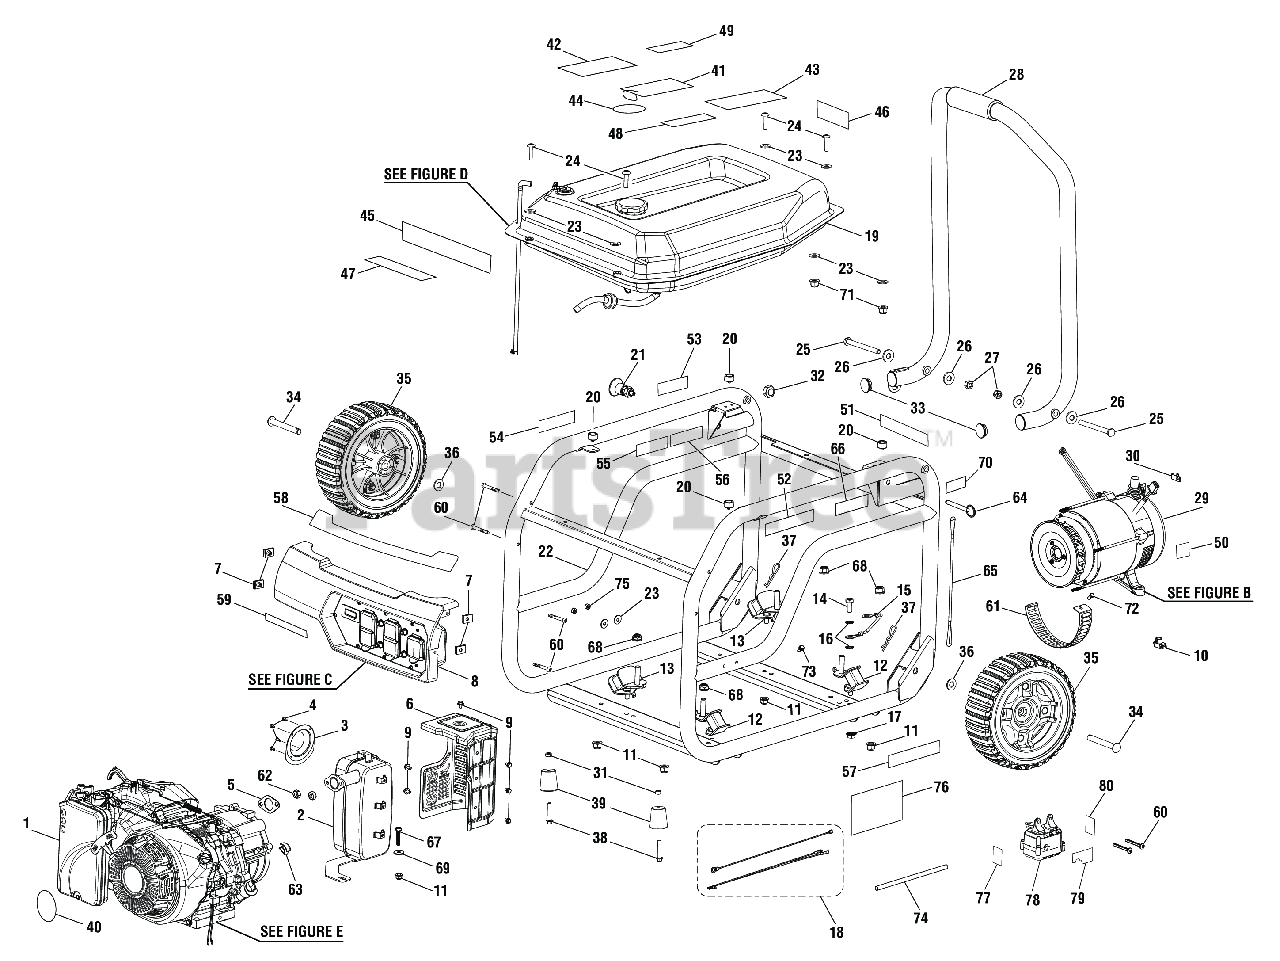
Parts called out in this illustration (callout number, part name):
3	Spark Arrester Screen
4	Screw (8-32 x 3/8 in., Pan Hd.)
5	Exhaust Gasket
6	Heat Shield
7	U-Clip (M6)
8	Power Head Assembly
9	Bolt (M6 x 9 mm, Hex Flange Hd.)
10	Rubber Wire Protector
11	Lock Nut (M8 x 1.25 mm, Flange)
12	Engine Isolator (Large)
13	Engine Isolator (Right)
14	Bolt (5/16-18 x 3/4 in., Hex. Hd.)
15	Assembly, ground wire
16	Washer (5/16 in., External Star)
17	Flange Nut (5/16-18, Hex Hd.)
18	Wire Assembly
19	Fuel System
20	Handle Bumper
21	Quick Release Pin Assembly
22	Carrier Assembly
23	Washer (1/4 in., Type A)
24	Screw (1/4-20 x 1 in., T30 Torx Hd.)
25	Handle Pivot Pin (5/6-18 x 90 mm)
26	Washer ( 5/16 in.)
27	Lock Nut (5/16-18, Hex Hd.)
28	Handle Assembly
29	Generator Head Assembly
30	Ground Lug (5/16-24) (BM903600)
31	Lock Nut (M8 x 1.25)
32	Lock Nut (1/2-20, Hex)
33	End Cap (Handle)
34	Washer (M10)
35	Handle Isolator
36	Washer (OD19.75 x ID10.5 x 1t)
37	Hitch Pin (M3)
38	Bolt (M8 x 1.25 in., Flange Hex Hd.)
39	Foot Assembly
40	Engine Recoil Label
41	Warning Hangtag
42	Warning Label
43	CPSC (English) Label
44	Remove Cap Fuel Stabilizer Label (English)
45	Logo Label
46	Combustion Label
47	Start Label
48	Fuel Stabilizer Label (French/Spanish)
49	No E85 Label
50	Ground Label Icon
51	Ground Warning Label
52	Risk of Fire Danger Label
53	Quick Release Pin Label
54	Exhaust Direction Label
55	Hot Surface and Exhaust Label
56	Fire Distance Label (Eng/Sp)
57	Engine Lubricant Label
58	Performance Label
59	Choke Label
60	Screw (M6 x 50 mm, T30 Torx Pan Hd. )
61	Fan Cover (Generator Head)
62	Hex Nut (M8 x 1.25, Special)
63	Plug (Generator Head)
64	Release Pin (5/16 x 2 in.)
65	Lanyard (3/16 in.)
66	Inquires Label (Ryobi)
67	Screw (M8 x 40 mm, Hex Hd.)
68	Lock Nut (5/16-18)
69	Washer (ID9 x OD25.4 x 2t)
70	Lock Pin Label
71	NYLON LOCK NUT (1/4-20)
72	Screw (M5 x 10 mm, Hex Hd.)
73	Bolt (M5 x 10 mm, Flange Hex Hd.)
74	Heat Shrink Tube
75	Lock Nut (M6 x 1 mm)
76	Auto Shut-Off Hang Tag
77	CO Shut-Off Label (English/Spanish)
78	CO Detector Shutdown Module
79	CO Monitor LED Label
80	CO Do Not Tamper (French/Spanish)
